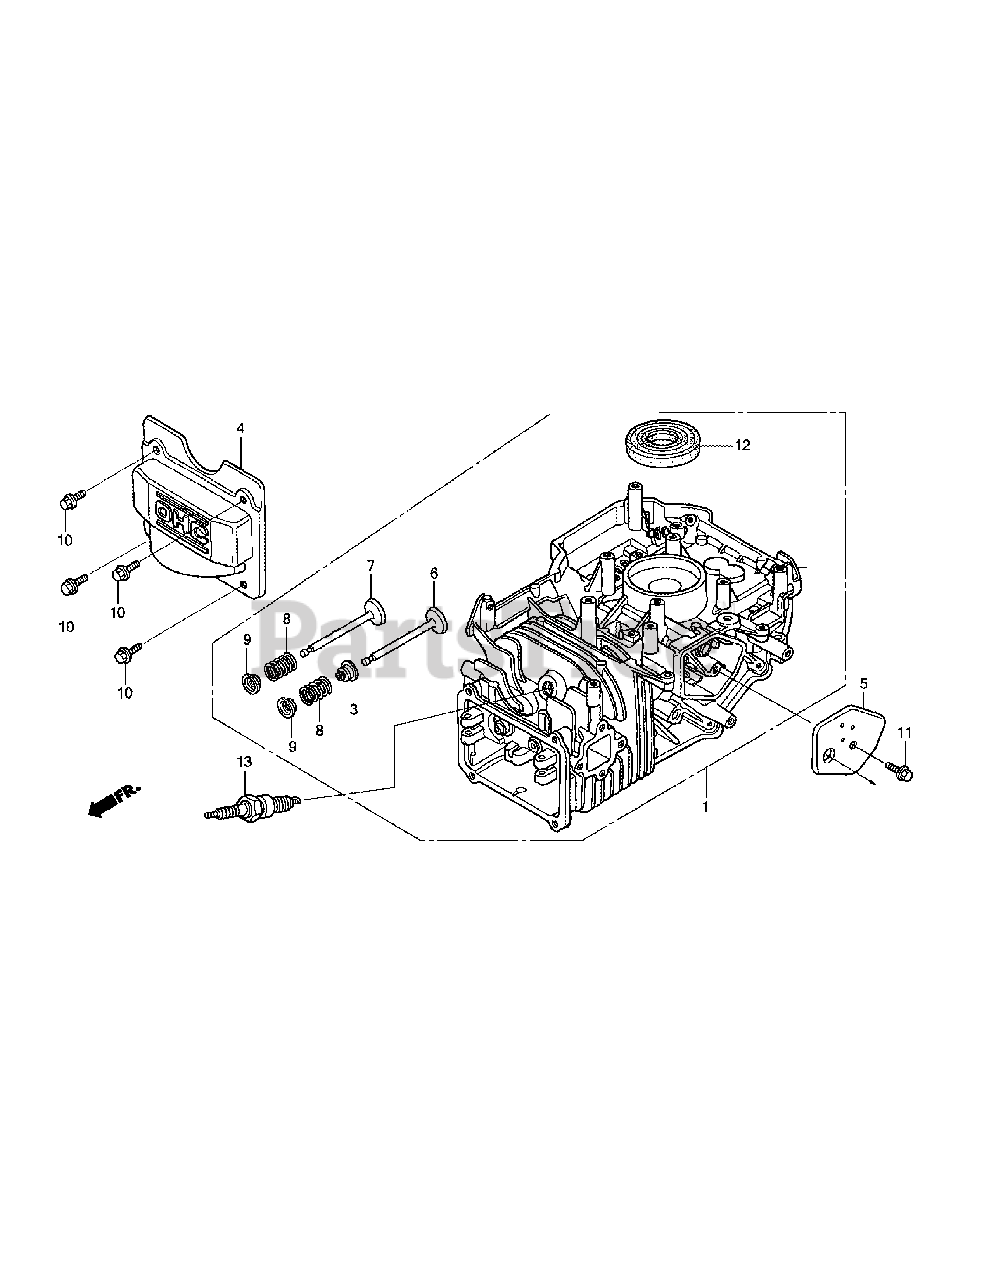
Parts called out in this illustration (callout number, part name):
1	Cylinder Assembly
3	Valve Stem Seal
4	Head Cover
5	Cover, Breather
6	Intake Valve
7	Exhaust Valve
8	Valve Spring
9	Valve Spring Retainer
10	Flange Bolt, 6 x 12
11	Flange Bolt, 6 x 14
12	Oil Seal, 25.4 x 62 x 6
13	SparkPlug,BPR6ES(NGK)
